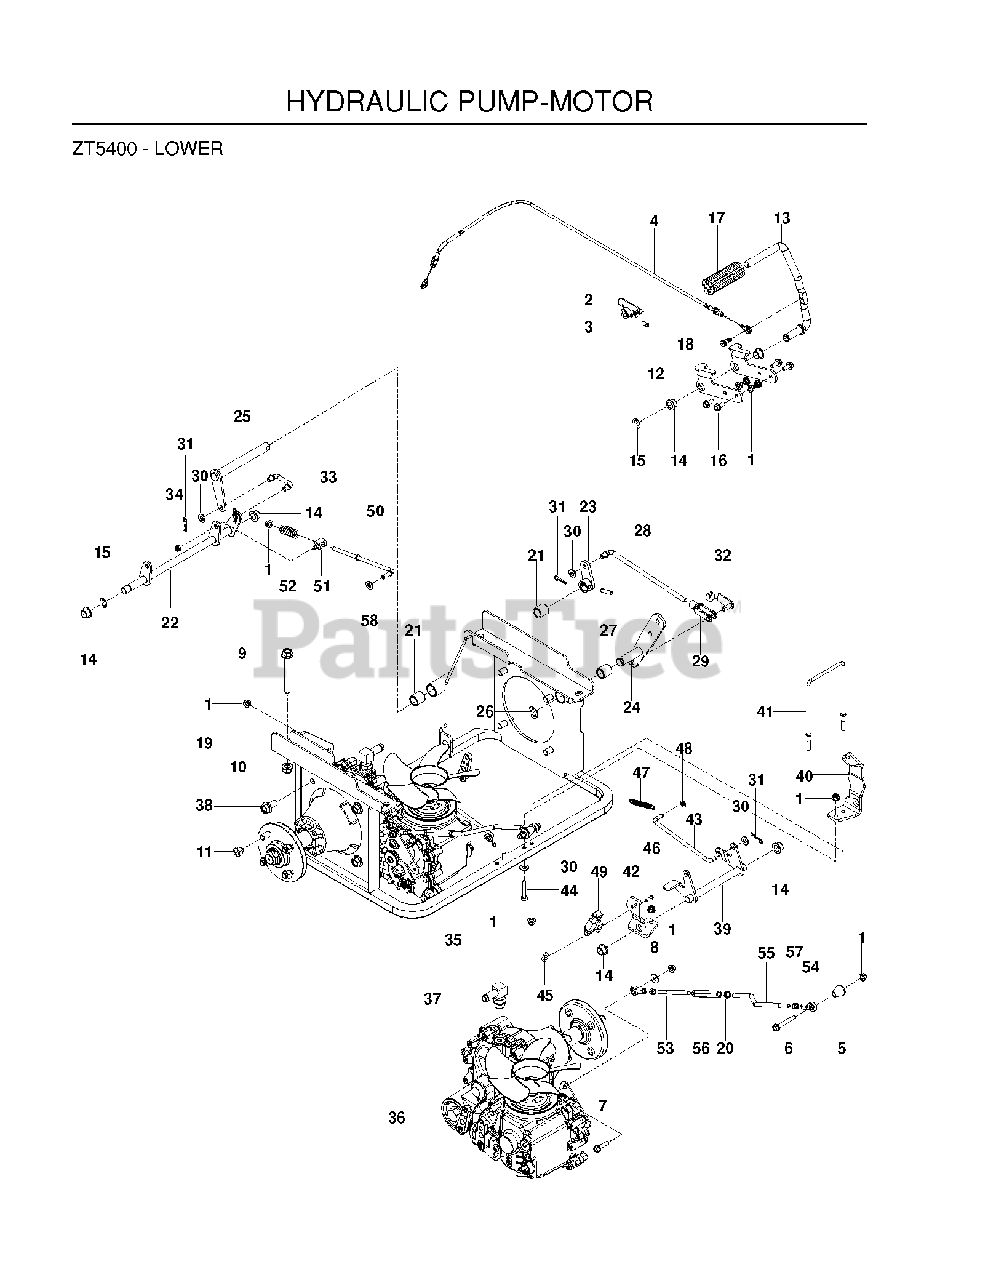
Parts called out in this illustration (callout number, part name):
1	5/16-18 NYLOC FLANGE NUT
2	BRACKET, CABLE, WELDED
3	SCREW 5/16C X 5/8 SQ HEAD
4	CABLE, TWO SPEED
5	SPACER, TAPPERED, 1.0"
6	HHFS 5/16-18 X 2.25 GD 5
7	HHFS 5/16-18 X 1.25 TPBLT GD 5
8	WASHER 5/16 FLAT
9	HHFS 1/2-13 X 4.0 GD8 ZD
10	NUT, 1/2-13 HEX FLG NYLOC ZD
11	LUG NUT 1/2F
12	BRACKET, PEDAL
13	LEVER, PEDAL
14	BUSHING, FLANGE, 5/8
15	E-RING 5/8
16	HHFS 5/16-18 X 3/4
17	PAD, FOOT PEDAL
18	BOLT, SHLD 3/8 X 5/16, 5/16-18
19	FRAME, ZT5400, BLACK
20	NUT 3/8-24 JAM
21	BUSHING, SLEEVE 3/4 X 1.0
22	SHAFT, BRAKE LOWER, WELDED
23	ARM, RT BRAKE
24	LEVER, LOWER, BRAKE
25	SHAFT, BRAKE, WELDED
26	E RING 3/4
27	5/16 DIA ROLL PIN
28	LINKAGE, BRAKE, UPPER
29	YOKE-3/8-24 PLTD
30	WASHER 3/8 SAE FLAT
31	HAIRPIN #2
32	PIN, CLEVIS SPRING, 3/8
33	LINKAGE, BRAKE, MIDDLE
34	5/16-18 THIN PROF NY
35	HG_ZT5400, LT
36	HG_ZT5400, RT
37	FITTING, 4601-10-10 NOW
38	HHFS 1/2-13 X 1 GR5 ZD
39	CRANK, TWO SPEED
40	BRACKET, TWO SPEED, LT
41	ROD, BELT KEEPER
42	BRACKET, TWO SPEED, RT
43	LINKAGE, TWO SPEED
44	HCS 5/16C X 1 3/4
45	TAPPED PLATE
46	SCR #10-24 X .75 SKT HD BLK
48	PUSH NUT
49	SWITCH, PLUNGER, SEALED
50	LINKAGE, BRAKE, LOWER
51	SWIVEL, BRAKE
53	LINKAGE, CONTROL, FT
54	BALL JOINT, RIGHT HANDED
55	ROD, CONTROL
56	TURNBUCKLE, 3/8
58	RT HEADLIGHT REFLECTOR
